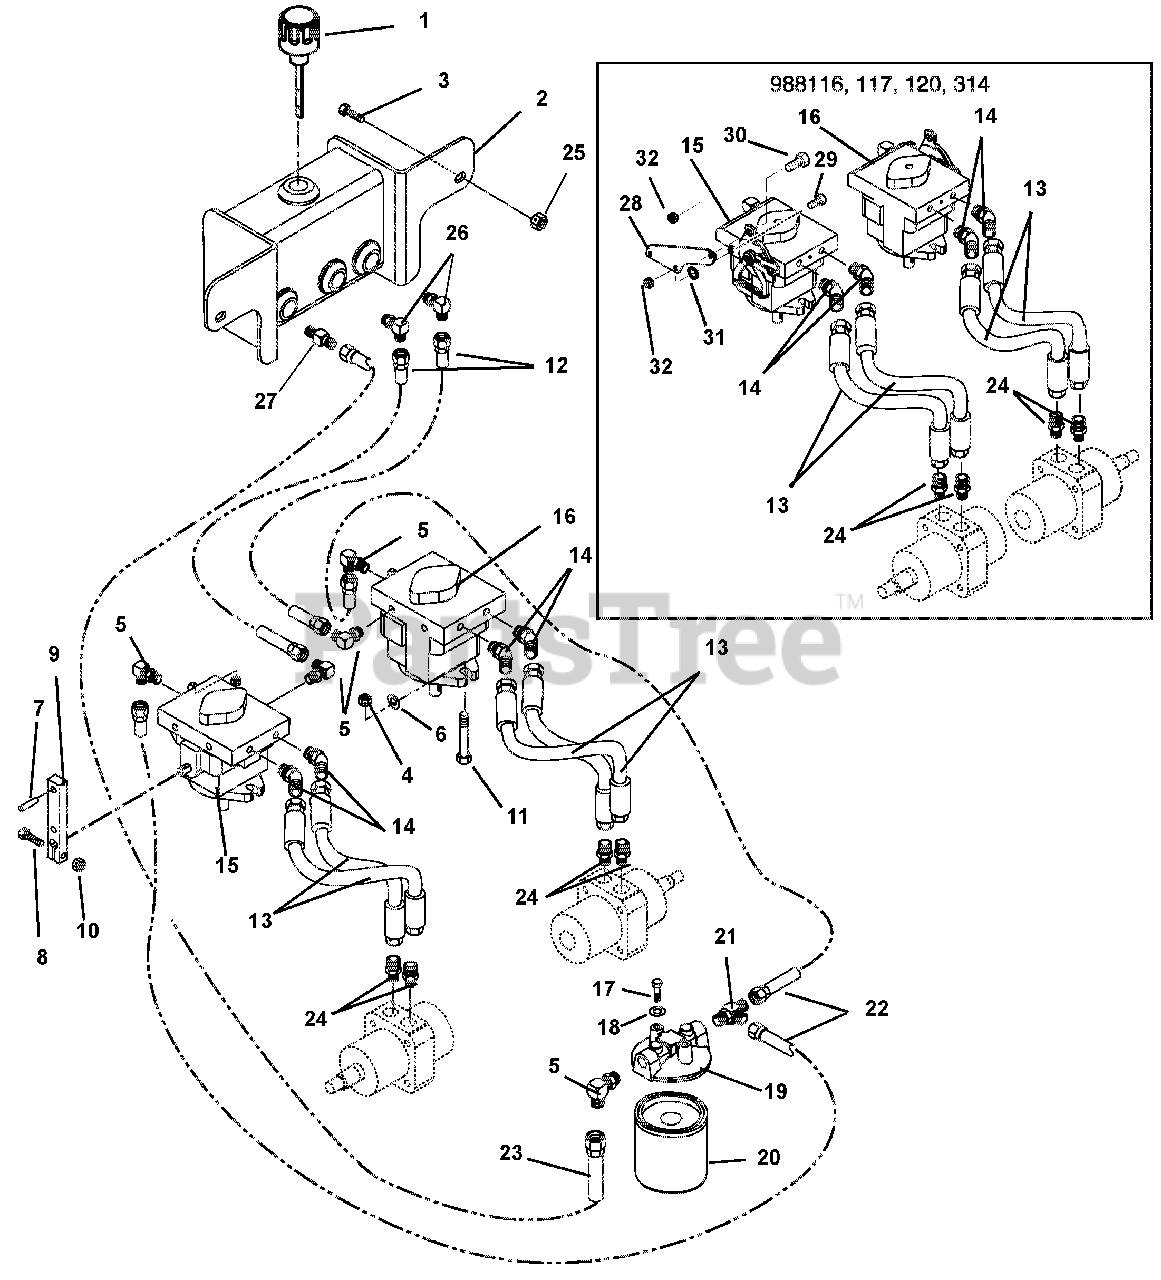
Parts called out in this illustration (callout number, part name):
1	Breather, Dipstick
2	Tank Assembly, Hydraulic
3	Bolt-Hex .38-16 x 1.00 Grade 5
4	Nut-Nylon-Locking .44-14
5	Fitting, Hydraulic
6	Washer-Flat-Steel .43 x 1.00 x .16
7	Pin-Dowel .312 x 1.25 (106, 108, 109)
8	Bolt-Hex .25-20 x 1.25 Grade 5 (106, 108, 109)
9	Arm, Pump Actuating (106, 108, 109)
10	Nut-Locking-Nylon .25-20 (106, 108, 109)
11	Bolt-Hex .44-14 x 1.50 Grade 5
12	Hose, Hydraulic
13	Hose, Hydraulic
14	Fitting, Hydraulic
15	Pump, Hydraulic Right Hand (106, 108, 109)
16	Pump, Hydraulic Left Hand (106, 108, 109)
17	Bolt-Hex .25-20 x .50 Grade 5
18	Washer-Locking .25 x .062 Regular
19	Head, Filter
20	Filter- Oil
21	Fitting, Hydraulic Tee
22	Hose, Hydraulic
23	Hose, Hydraulic
24	Adapter, Face Seal 10 x 8.625 O-Ring
25	Nut-Locking-Nylon .38-16
26	Hydraulic, Fitting Elbow
27	Hydraulic, Fitting Straight
28	Bracket, Return to Neutral/Damper (116, 117, 120, 314)
29	Bolt-Hex .31-18 x .50 Grade 5 (116, 117, 120, 314)
30	Bolt-Hex .31-18 x 1.00 Grade 5 (116, 117, 120, 314)
31	Bushing-Sleeve .377 x .624 x .370 (116, 117, 120, 314)
32	Nut-Locking-Center .31-18 (116, 117, 120, 314)
